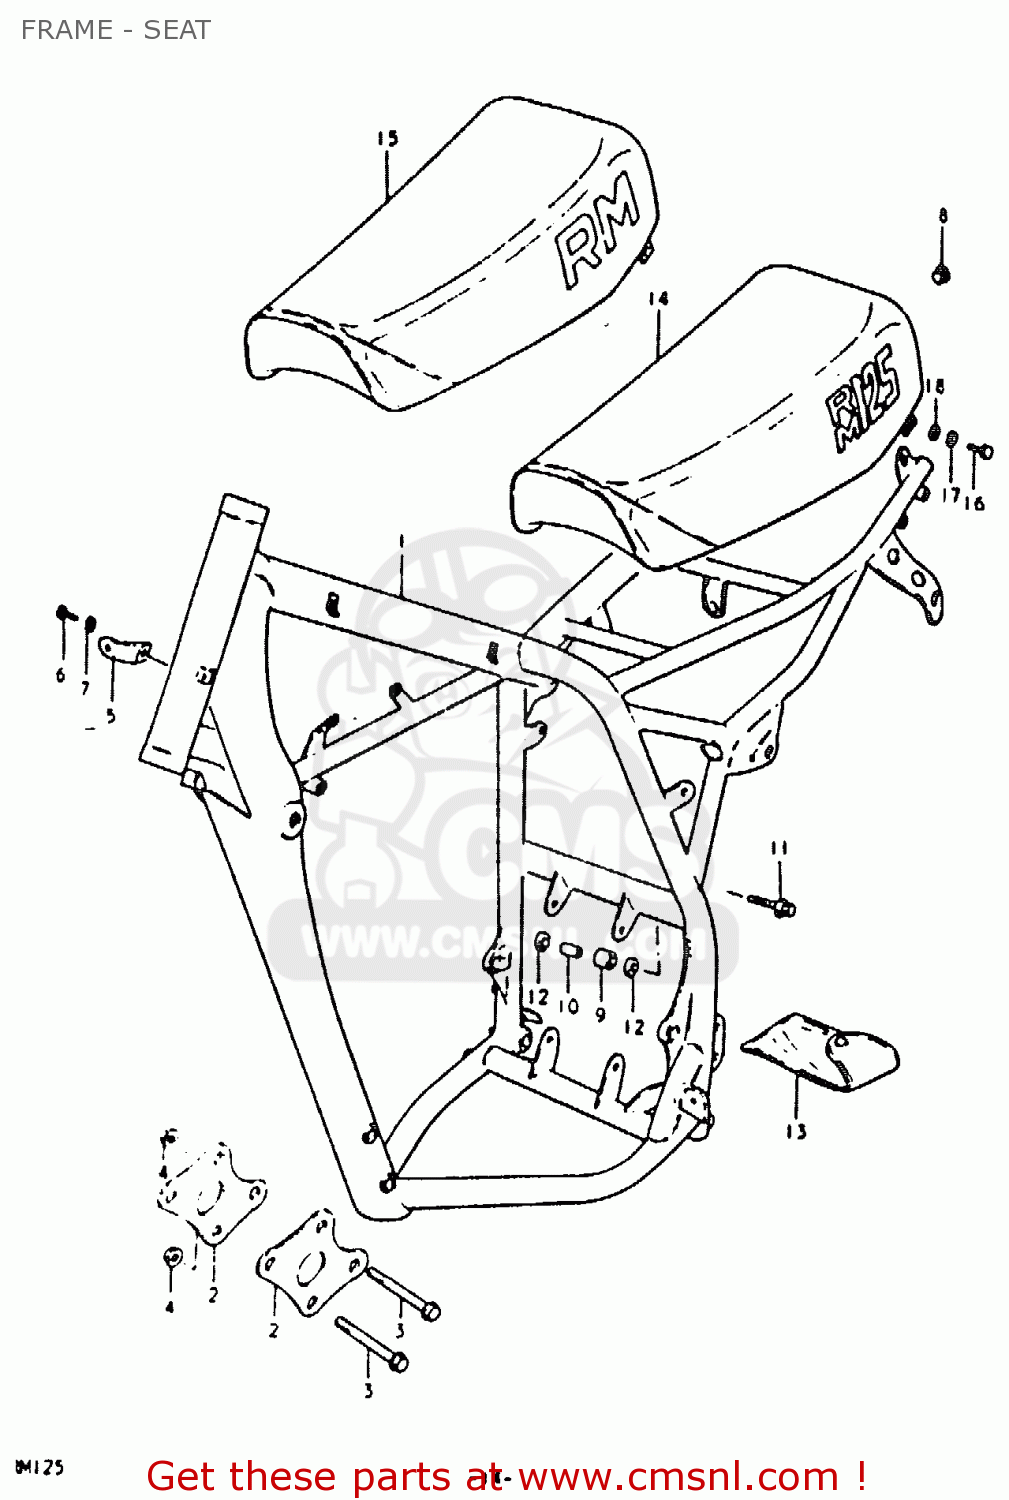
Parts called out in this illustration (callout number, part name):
1	FRAME
5	PLATE,ENGINE MOUNTING
6	BOLT
7	LOCK WASHER
8	PLUG(OD:19)
13	TOOL SET
14	SEAT ASSEMBLY
16	BOLT, UPPER
17	LOCK WASHER
18	WASHER(6.5X18X1)
